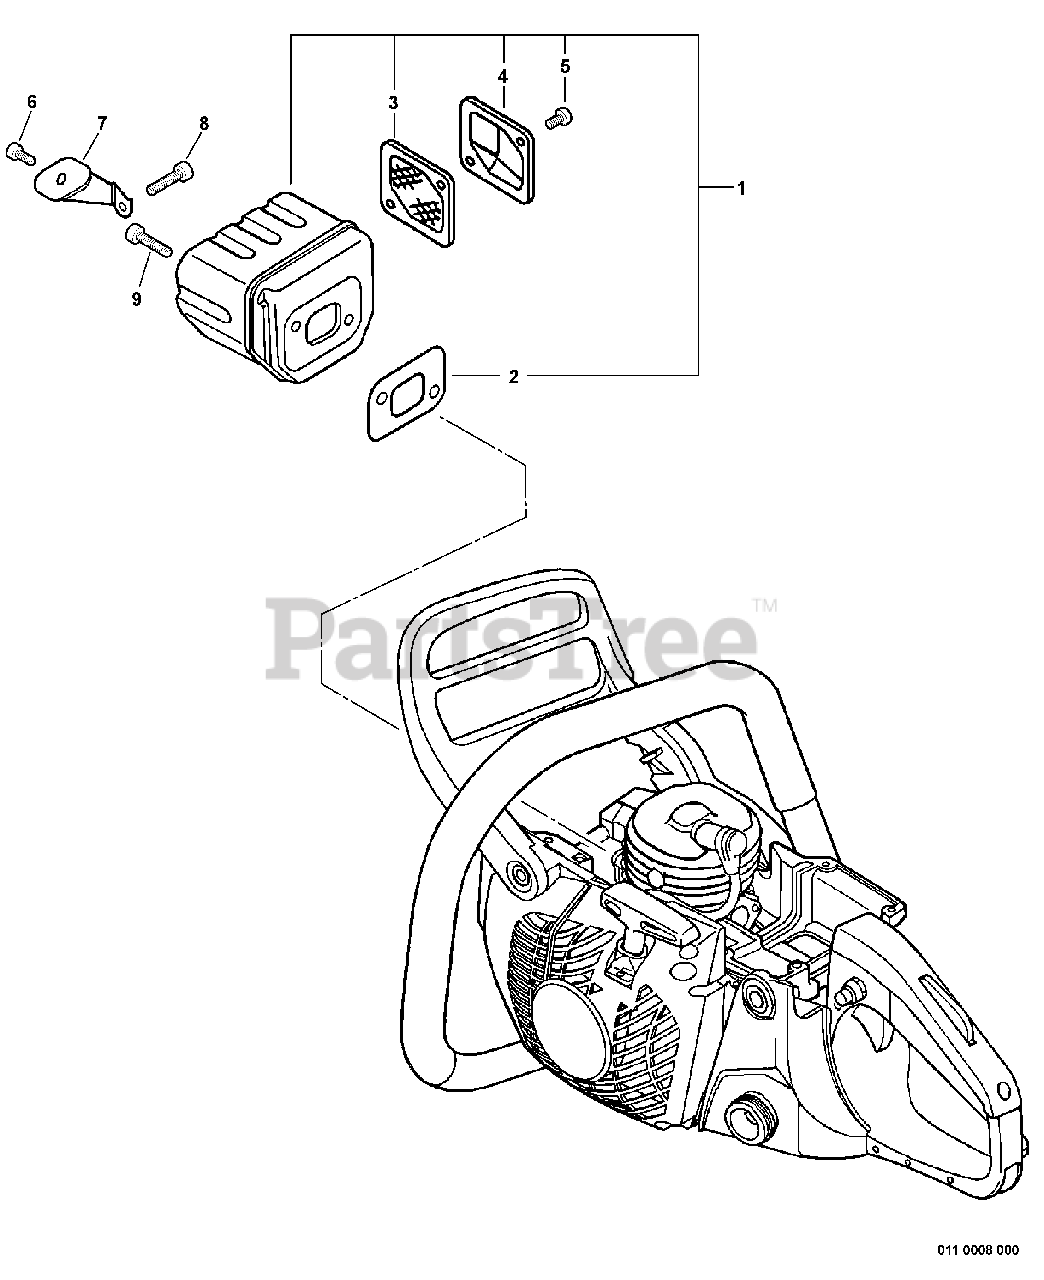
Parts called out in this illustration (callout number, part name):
1	MUFFLER ASSY
2	GASKET, EXHAUST
3	SCREEN, SPARK ARRESTOR
4	GUIDE, EXHAUST
5	SCREW - 4X8
7	BRACKET, MUFFLER
8	SCREW - 6X14
9	SCREW - 5X14
